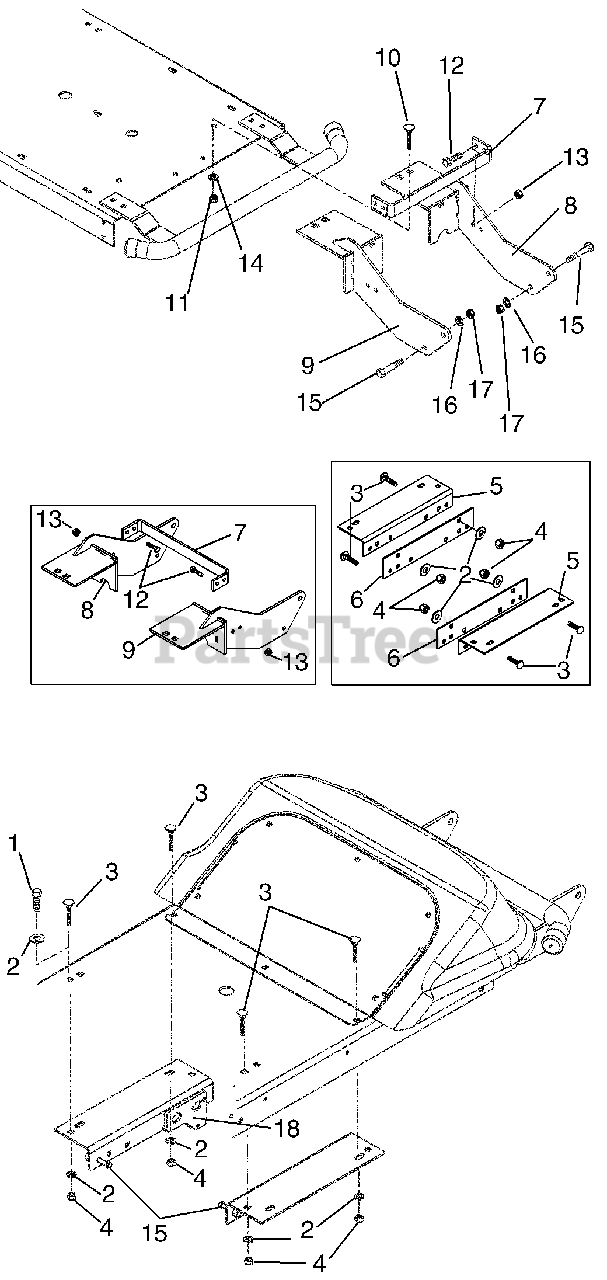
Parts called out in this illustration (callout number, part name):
1	Bolt-Hex .38-16 x 1.00
2	Washer, .38
3	Bolt, Carriage .38-16 x 1.00 Grade 5
4	Nut, .38-16 Lock (Nylock)
5	Bracket, Frame
6	Bracket, Extension
7	Bracket, Hitch
8	WSHR-FL-STL .323X.625X.062 PL
9	WSHR-FL-STL .505X.880X.072 PL
10	Bolt, Carriage .50-13 x 1.50 Grade 5
11	Nut, Hex .50-13
12	Bolt, Hex .312-18 x 1.00 Grade 5
13	Nut, Hex .312-18 Nylock
14	Washer, Lock Spring .50
18	Hanger Bracket
